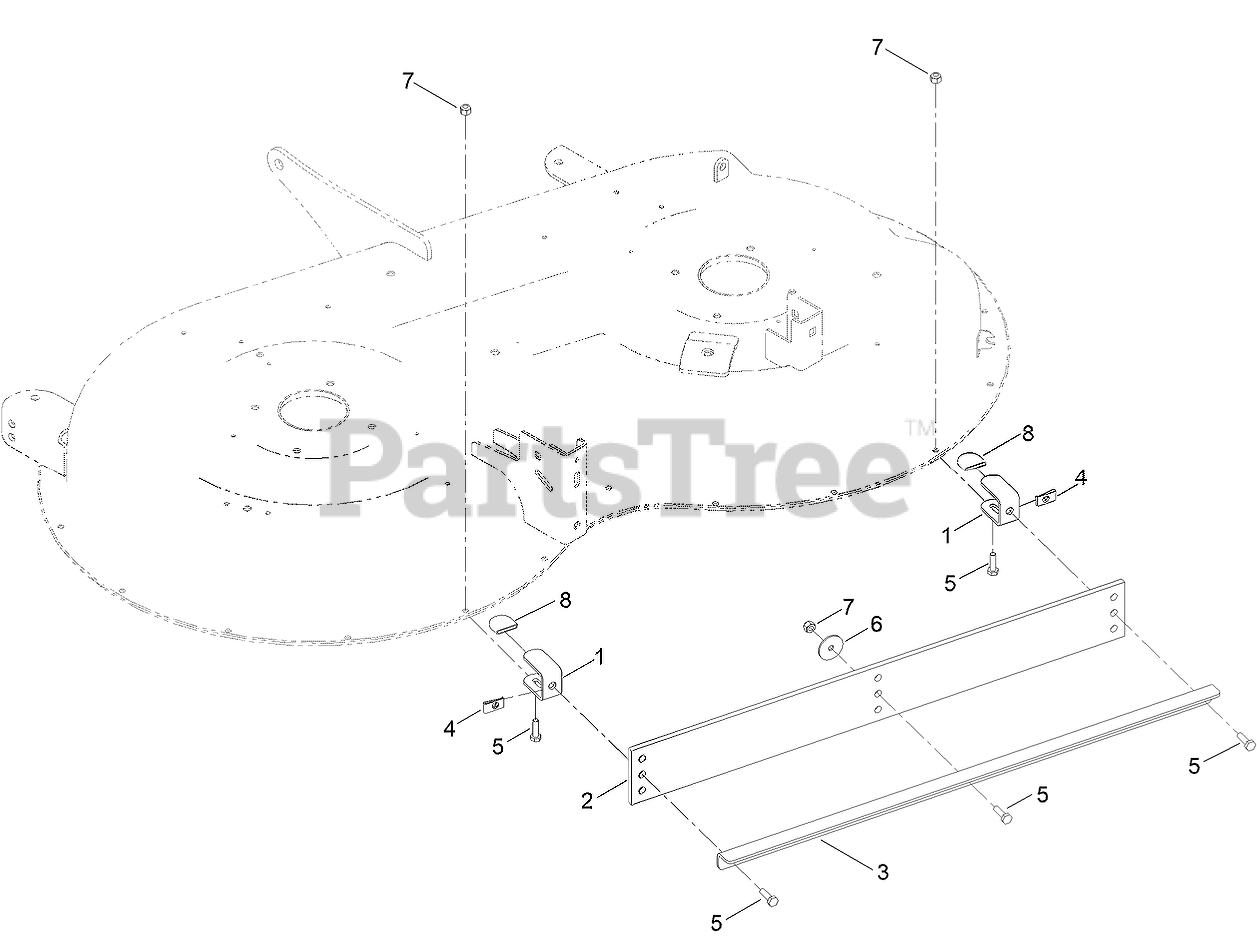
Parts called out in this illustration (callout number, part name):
1	BRACKET-MOUNTING
2	WIPER-STRIPING
3	BRACE-WIPER
4	NUT-SPEED
5	SCREW-HH
6	WASHER-FLAT
7	NUT-HEX
